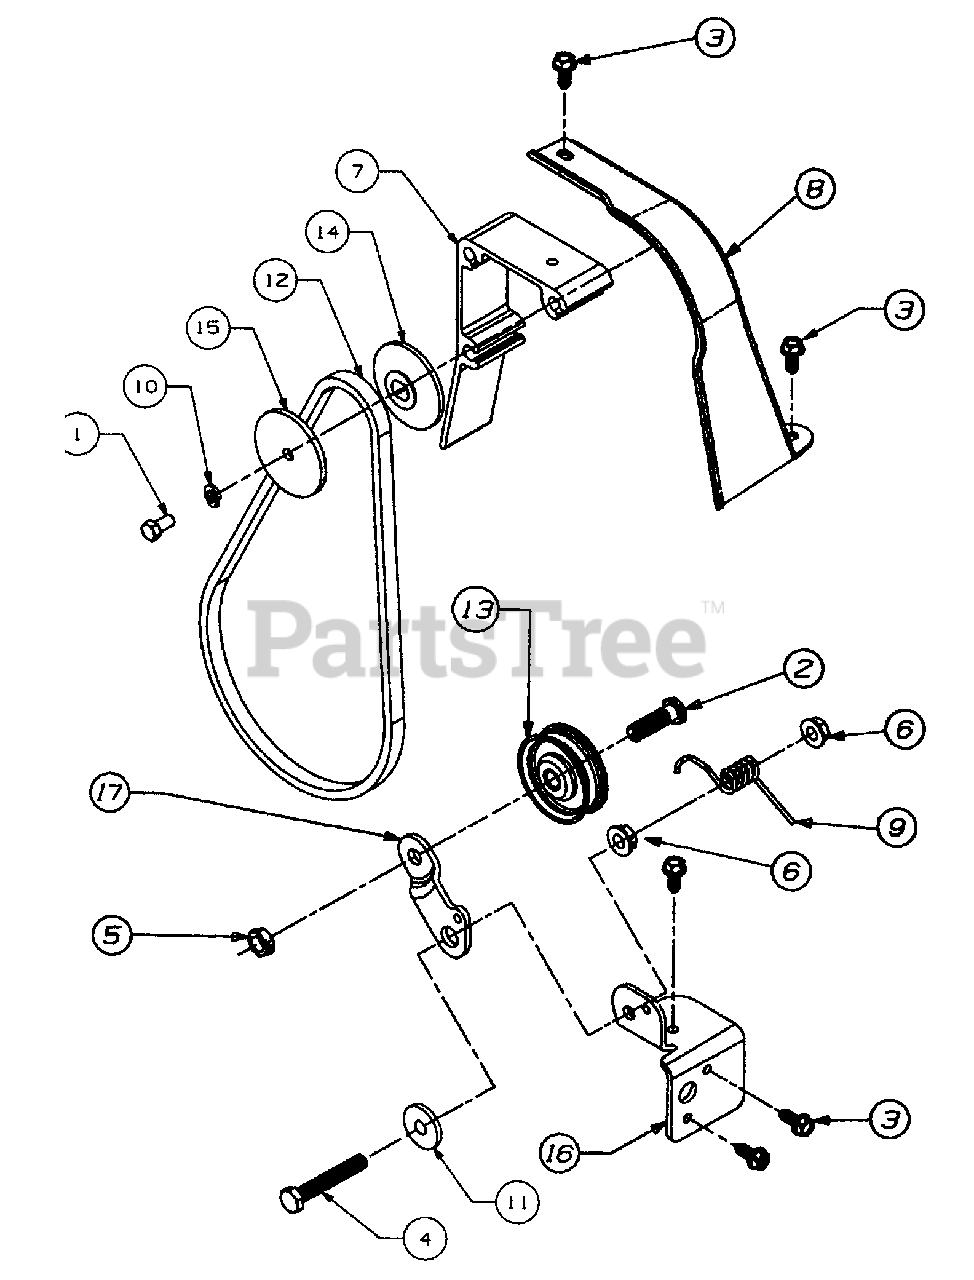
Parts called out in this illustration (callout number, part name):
1	SCREW-HEX
2	SCREW-HEX
3	SCREW-HEX
4	NUT-HEX SHOULDER
5	NUT-HEX LOCK
6	NUT-HEX LOCK FLANGE
7	ADAPTER-MOUNTING
10	WASHER-LOCK
11	HEX HEAD SCREW
12	V-BELT
13	IDLER-FLAT
14	PULLEY HALF
15	PULLEY HALF
